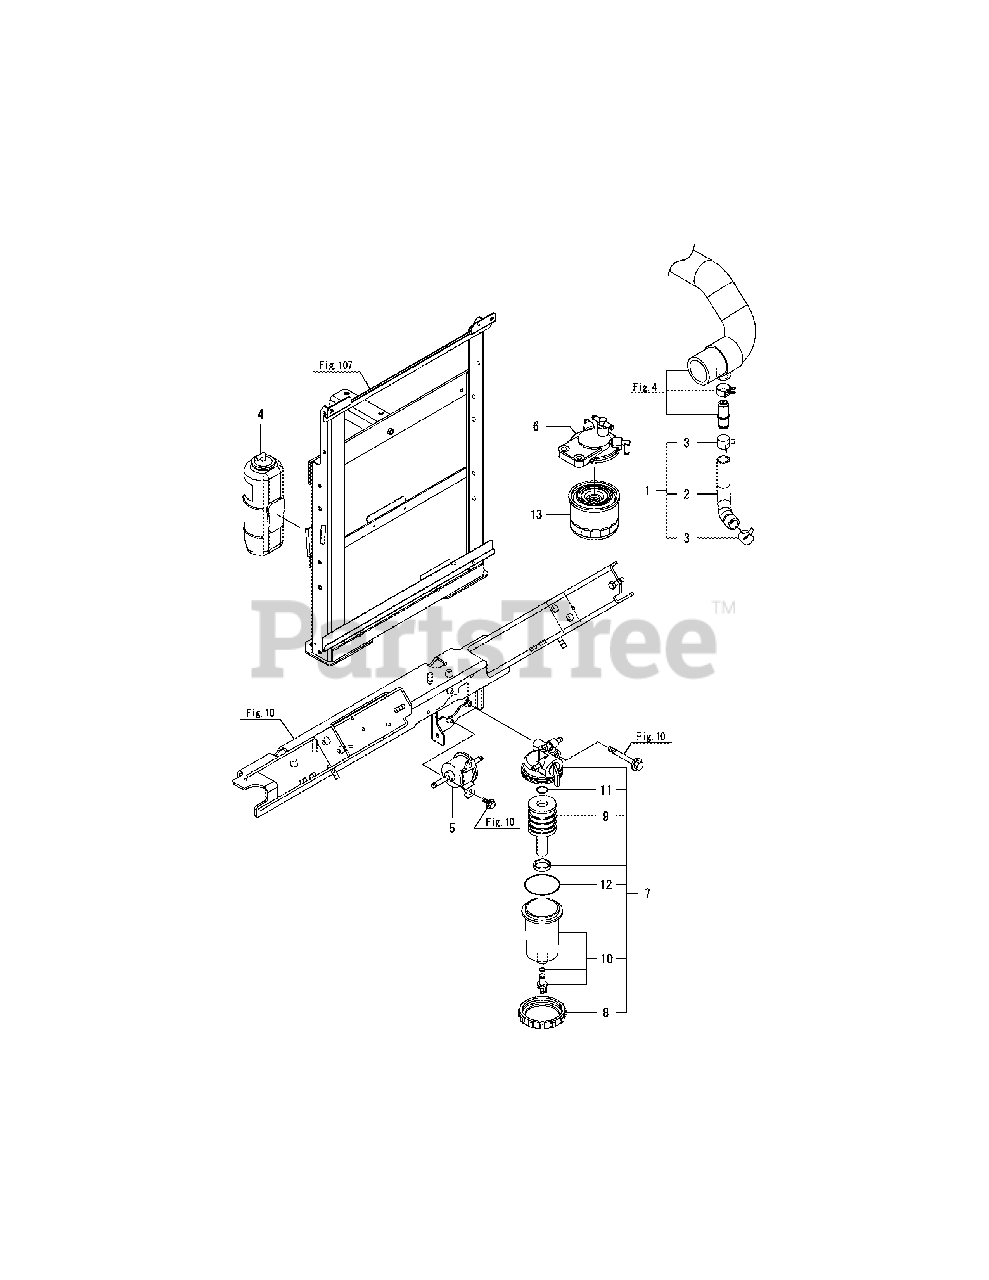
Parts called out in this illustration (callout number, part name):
1	HOSE ASSY, BREATHER
2	HOSE, BREATHER
4	TANK ASSY, SUB
5	PUMP ASSY, FUEL FEED
6	BRACKET, FILTER
7	SEPARATOR ASSY
8	RING, RETAINING
11	O-RING 1A P-16.0
12	O-RING 1A G-65.0
